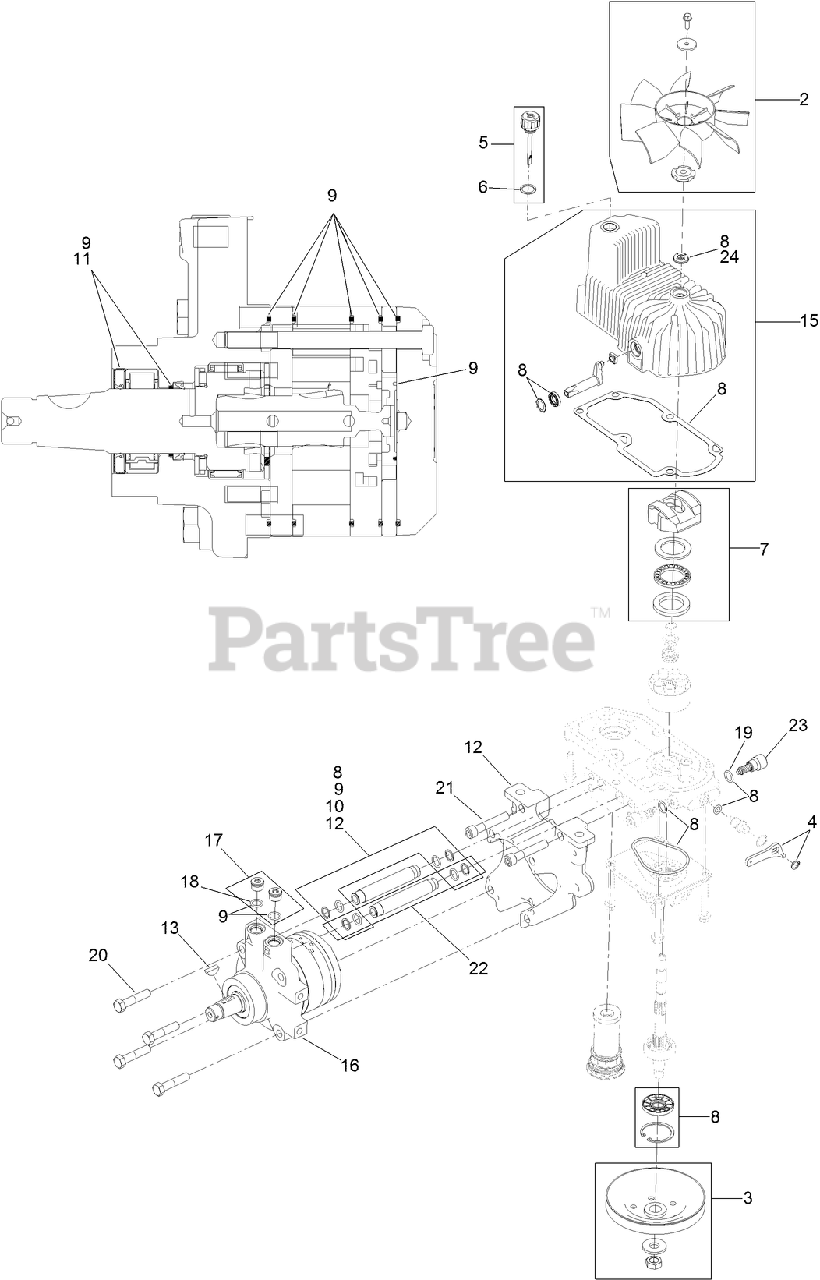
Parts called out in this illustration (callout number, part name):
2	FAN KIT
3	PULLEY KIT
4	HANDLE-BYPASS VALVE, HYDRO
5	DIPSTICK-HYDRO W/GASKET
6	GASKET-DIPSTICK, HYDRO
7	SWASH BLOCK KIT
8	PUMP SEAL KIT
9	MOTOR SEAL KIT
10	TUBE SEAL KIT
11	OUTPUT SHAFT SEAL KIT
12	NOSE CUP-UHT
13	KEY-WOODRUFF
15	Housing-LH
16	MOTOR-HYDRAULIC, LH 280CC
17	MAGNETIC PLUGS SERVICE KIT
18	O-RING
19	O-RING-CHECK VALVE
20	SCREW HH
21	SCREW-HSH
22	HYDRAULIC TUBE KIT
23	SHOCK VALVE, 16CC HYDRO
24	SEAL-FAN DRIVE
